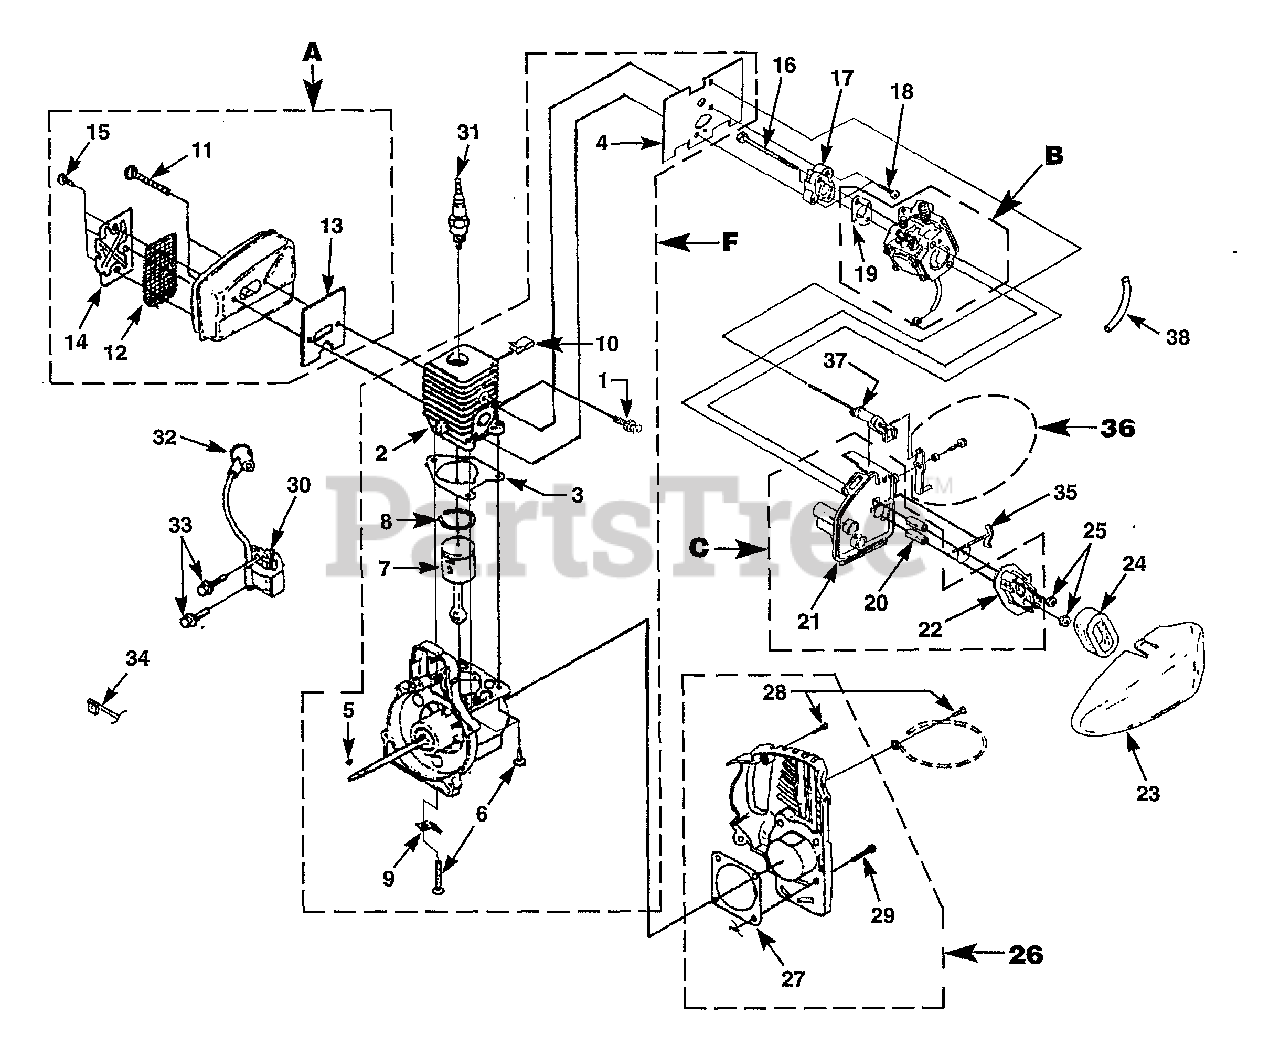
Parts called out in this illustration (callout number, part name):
1	COMPRESSION RELEASE VALVE
2	25CC CYLINDER KIT
3	GASKET-Cylinder
4	GASKET-Heat Dam
5	KEY-Woodruff
6	SCREW-Thread Form. (10-24 X 7/8")
7	25CC PISTON & ROD
8	RING-Piston
9	TERMINAL
11	SCREW-Machine (#10-24 X 2")
12	SCREEN-Spark
13	GASKET-Muffler
16	SCREW-Shoulder
17	HEAT DAM
18	SCREW-Taptite (10-24 X 1")
19	GASKET-Carburetor
22	BLADE RET. MAGNET
23	COVER-Air Filter
24	FILTER-Air
25	NUT-Hex (10-24)
26	CRANKCASE COVER
27	GASKET-Crankcase Cover
28	SCREW-Plastite (#10 X 3/4")
29	SCREW-Taptite (10-24 X 1")
30	MODULE-Ignition
31	SPARK PLUG
32	TERMINAL & COVER
33	SCREW-Taptite (8-32 X 1")
34	LEAD- Electrical
35	BLADE & SHAFT ASSEMBLY
36	BELLCRANK
37	CHOKE ACTUATOR
38	TUBING-Rubber (3")
F	SHORT BLOCK (25CC)
A	MUFFLER KIT
B	CARBURETOR KIT
C	AIR FILTER BODY
